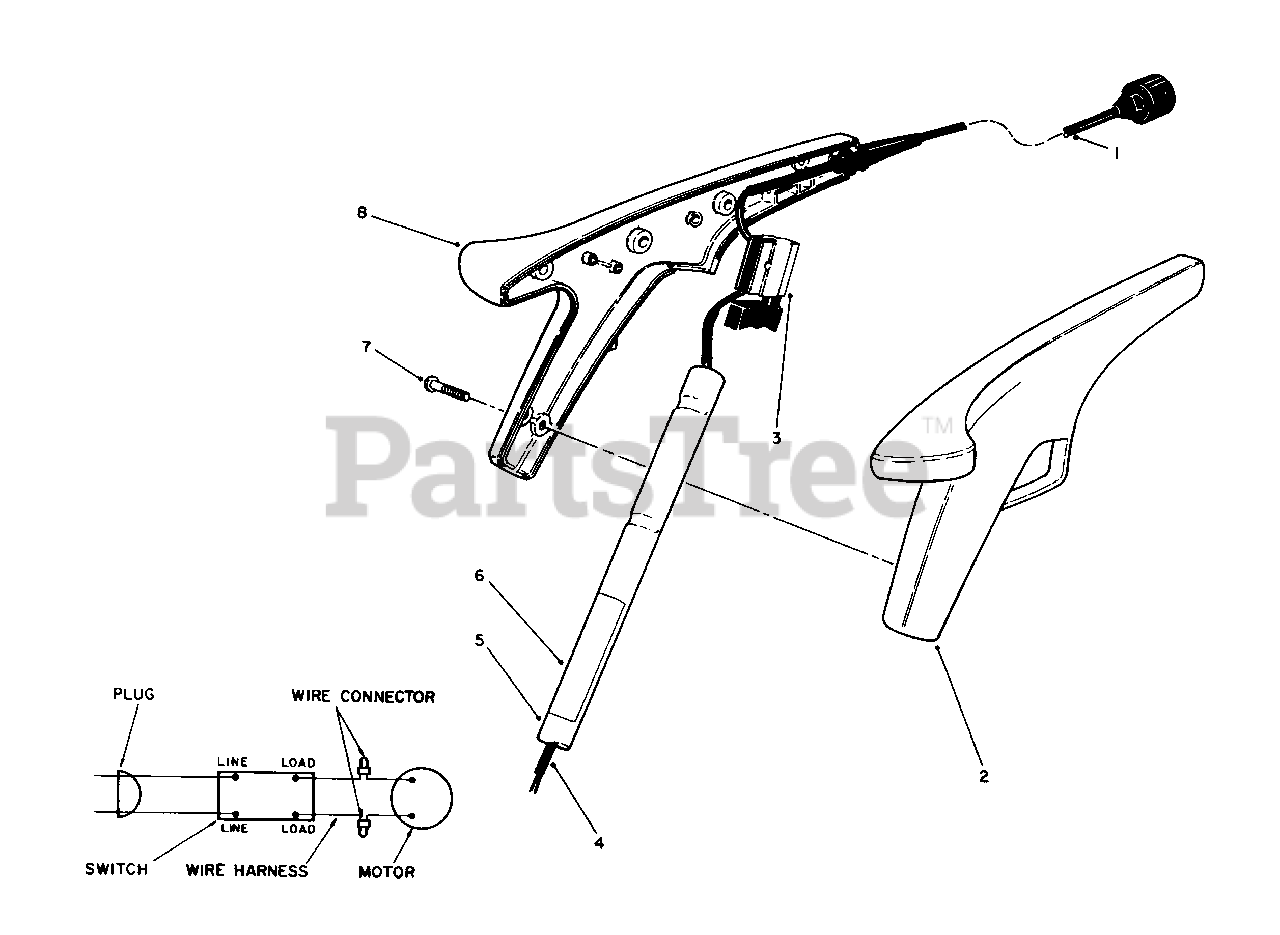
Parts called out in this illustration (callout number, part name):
1	Cord-Power
2	Grip-L.H.
4	Harness-Wiring
5	Tube-Handle Extension
8	Grip-R.H.
